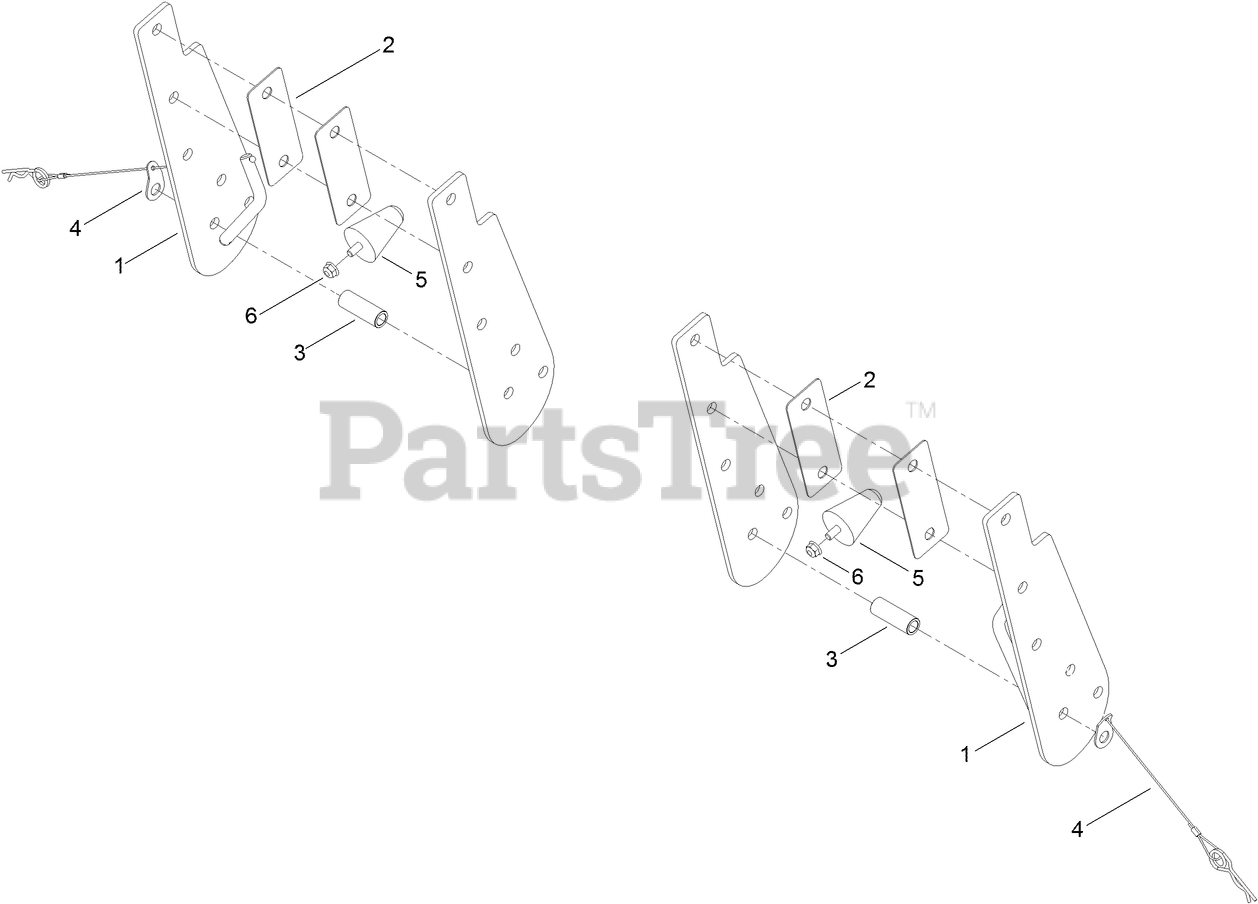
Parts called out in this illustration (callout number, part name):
1	BRACKET-PIVOT, ROPS
2	SPACER-ROPS
3	SPACER
4	PIN-ROPS
5	BUMPER-RUBBER
6	NUT-HF, NI
